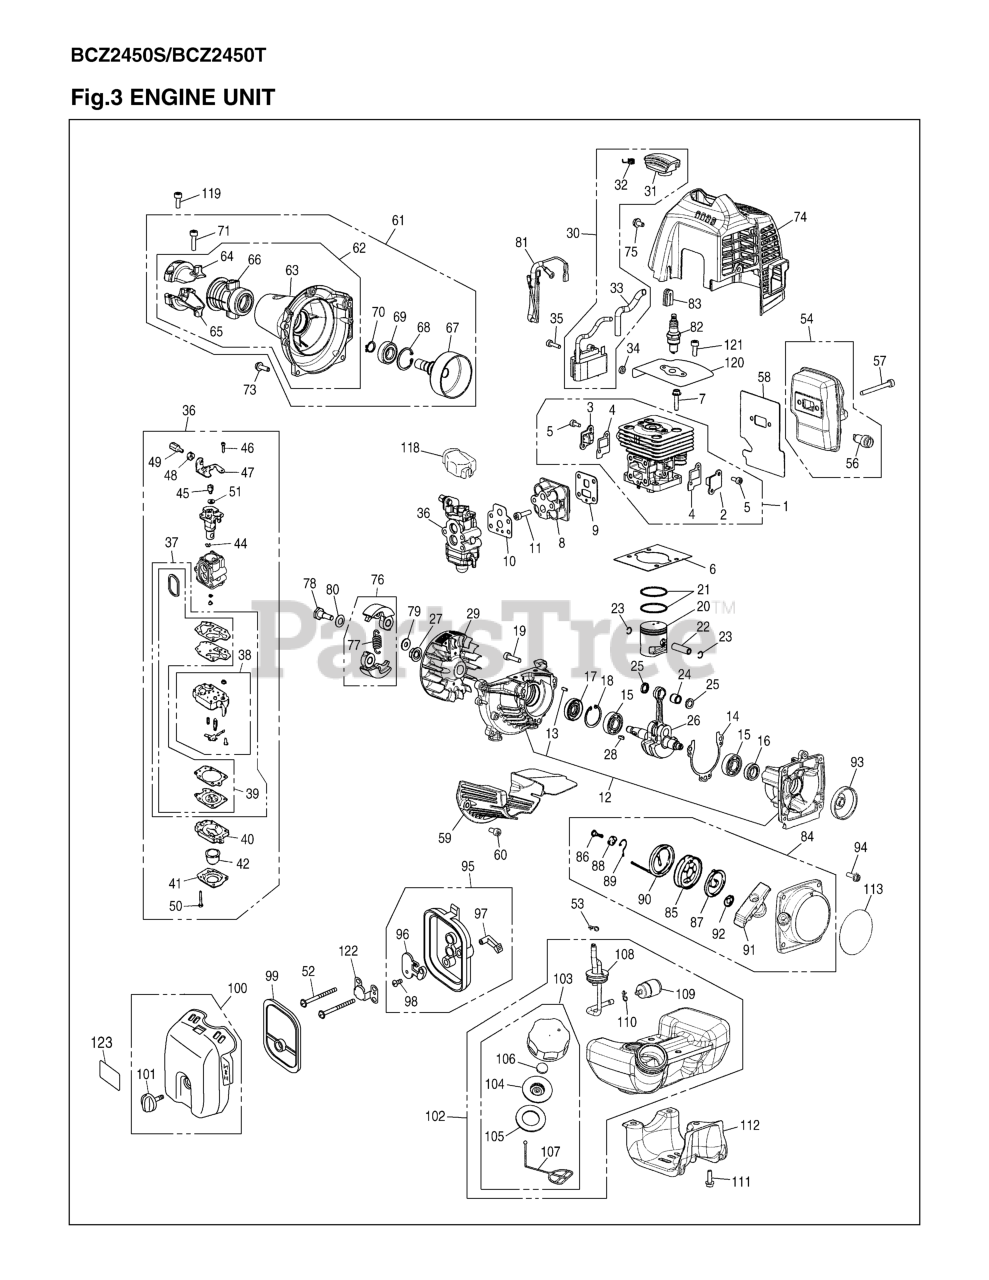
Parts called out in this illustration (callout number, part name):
1	CYLINDER COMP
2	COVER, TR-S
3	COVER, TR-F
4	GASKET, TR
5	BOLT
6	GASKET, BASE
7	BOLT
8	INSULATOR
9	INSULATOR GASKET
10	GASKET, CARB
11	BOLT, TORX
12	CRANKCASE-C
14	GASKET, CASE
16	SEAL
17	SEAL, OIL (RPLS
19	BOLT (RPLS 28501
21	RING, PISTON
22	PIN, PISTON
23	RING, SNAP (RPLS
25	WASHER
26	CRANKSHAFT-C
27	NUT (RPLS 1140-4
28	KEY
29	ROTOR
31	CAP(RPLS 4810721
35	BOLT TORX
36	CARBURETOR (RPLS
37	REBUILD KIT
38	BODY, PUMP
39	GASKET KIT
40	BODY, PURGE
41	COVER, PUMP
42	PUMP, PRIMING
49	SCREW
50	SCREW
51	WASHER
52	BOLT TORX
53	CLIP
56	ARRESTER
57	BOLT
58	GASKET, MUFFLER
60	BOLT
61	HOUSING ASSY (RP
62	HOUSING COMP (RP
63	HOUSING
64	BRACKET (A) (RPL
65	BRACKET (B)
66	CUSHION (RPLS T1
67	DRUM (RPLS 48103
69	BEARING
71	BOLT (RPLS 28501
73	BOLT
74	COVER, ENGINE
75	BOLT (RPLS T4950
76	SHOE COMP
77	SPRING
78	BOLT
79	WASHER
80	WASHER (RPLS 114
81	CORD COMP.
82	SPKPLUG(CMR7H)(R
83	GROMMET
84	RECOIL-A
85	REEL
86	SCREW
87	SPRING, SPIRAL
88	COLLAR
89	ARM
90	ROPE (RPLS 45007
91	KNOB (RPLS 3330-
92	PLATE, STOPPER
93	PULLEY
94	BOLT, TORX
95	CLEANER BODY ASS
96	PLATE, CHOKE
98	SCREW
99	ELEMENT
100	CLEANER COVER AS
101	CLEANER KNOB
102	TANK ASSY
103	CAP ASSY
104	HOLDER (RPLS 450
105	PACKING
106	FILTER
107	STOPPER
108	PIPE-C
109	FILTER
110	CLIP (RPLS 28413
111	BOLT
112	GUARD, TANK
113	LABEL, RECOIL
118	COVER
119	BOLT
121	BOLT
